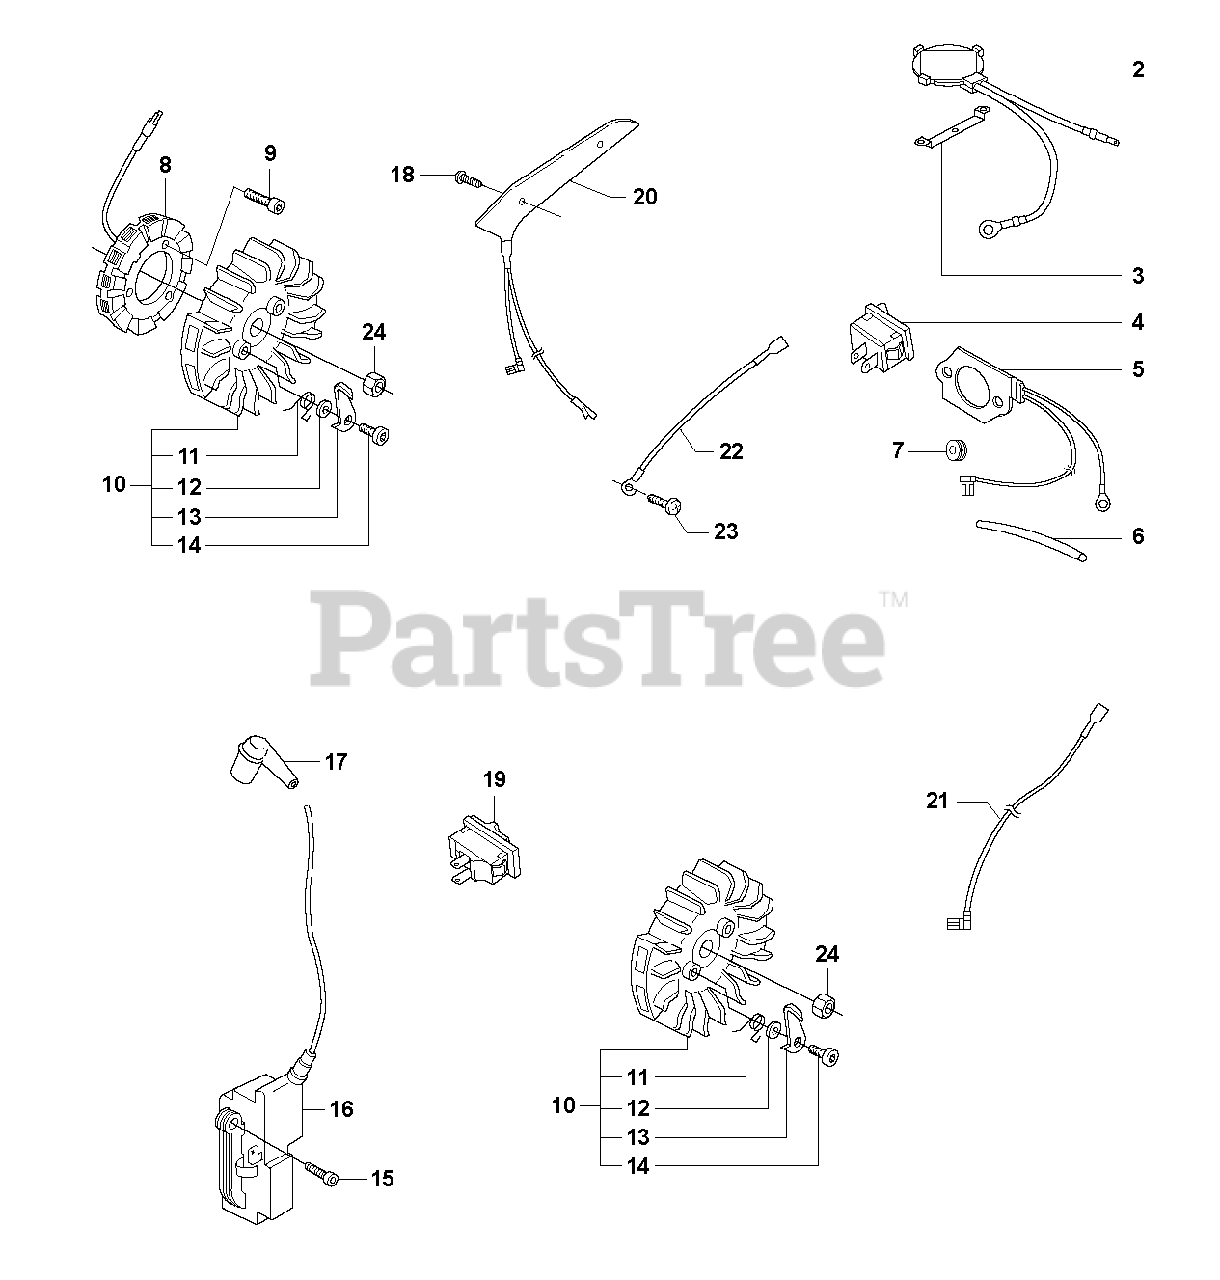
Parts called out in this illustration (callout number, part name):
2	THERMOSTAT
3	BRACKET
4	SWITCH
5	FOIL ELEMENT
6	TUBE
7	GROMMET
8	GENERATOR
9	SCREW
10	FLYWHEEL
11	SPRING
12	WASHER
13	PAWL
14	SCREW M5X14
16	IGNITION MODULE
17	SPARK PLUG CONN. KIT
19	START/STOP SWITCH
20	PLATE (G)
24	NUT W/ WASHER
